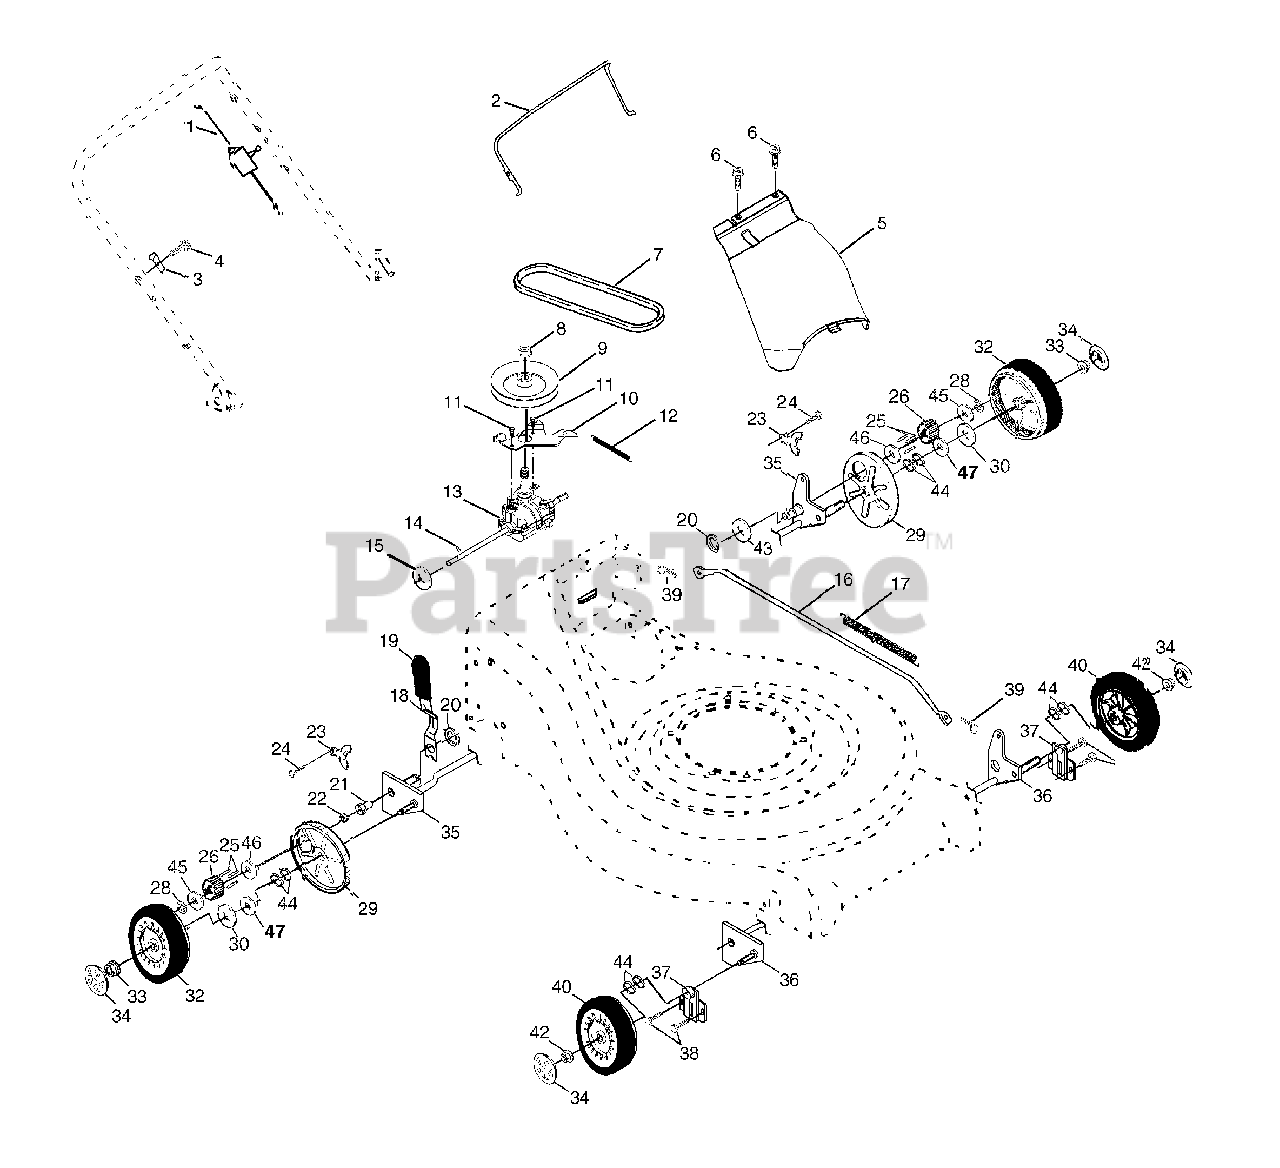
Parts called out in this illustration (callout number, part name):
1	Cable Drive
2	Bail Control Drive
3	Bracket, Downstop
4	Screw Hex Wash Head Tapping 10-2
5	Cover Drive
6	Screw Thdrol 10-25 x .50
8	Nut Lock Flanged 3/8-16 Zinc
9	Pulley Driven
10	Belt Keeper
11	Screw Hex Wash Head 10-24 X .668
13	Transmission Asm.
14	Pin Spring Thrust
15	Washer Hardened
16	Rod Connecting
17	Spring Extension
18	Spring Selector
19	Knob Selector Spring
20	E-Ring 7/8
21	Bearing Support
22	Bearing Ball
23	Retainer Drive Asm. Stmp.
24	Screw Hex Head Tapping 1/4-20 x .75
25	Drive Pawl
26	Pinion, Drive
28	E- Ring 7/16
29	Cover, Dust Wheel
30	Washer 1/2 x 1-1/2 x .134
32	Wheel 9 x 2
33	Nut Hex Flange Lock
35	Shaft Asm. Rear
36	Shaft Asm. Front
37	Retainer Front Shaft
38	Screw 12 x 5/8
39	Clip Retainer
40	Wheel 8 x 2
42	Nut, Hex Flange Lock 3/8-16
44	Wave Washer
47	Felt Washer
